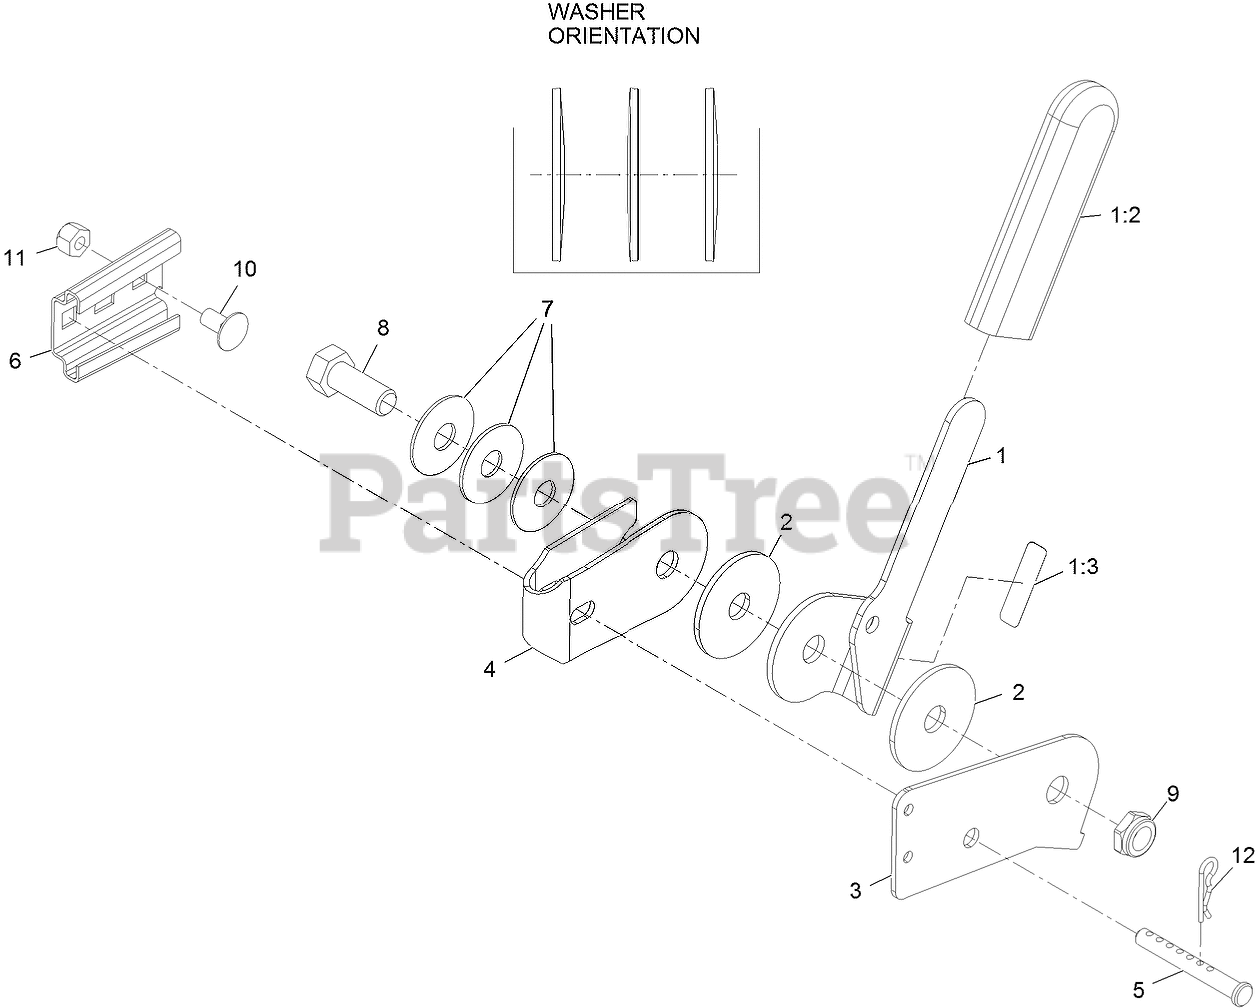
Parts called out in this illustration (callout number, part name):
1	CONTROL HANDLE ASM-OCD
1:2	GRIP-LEVER
1:3	Decal-Operation
2	DISC-FRICTION
3	BRACKET,CONTROL MOUNT
4	BRACKET,HANDLE MOUNT
5	PIN-CLEVIS
6	BRACKET-MOUNTING,SMV
7	WASHER-DISC, SPRING
8	SCREW-HH
9	NUT-HEX
10	SCREW-CARR
11	NUT-LOCK, NI
12	PIN-COTTER
